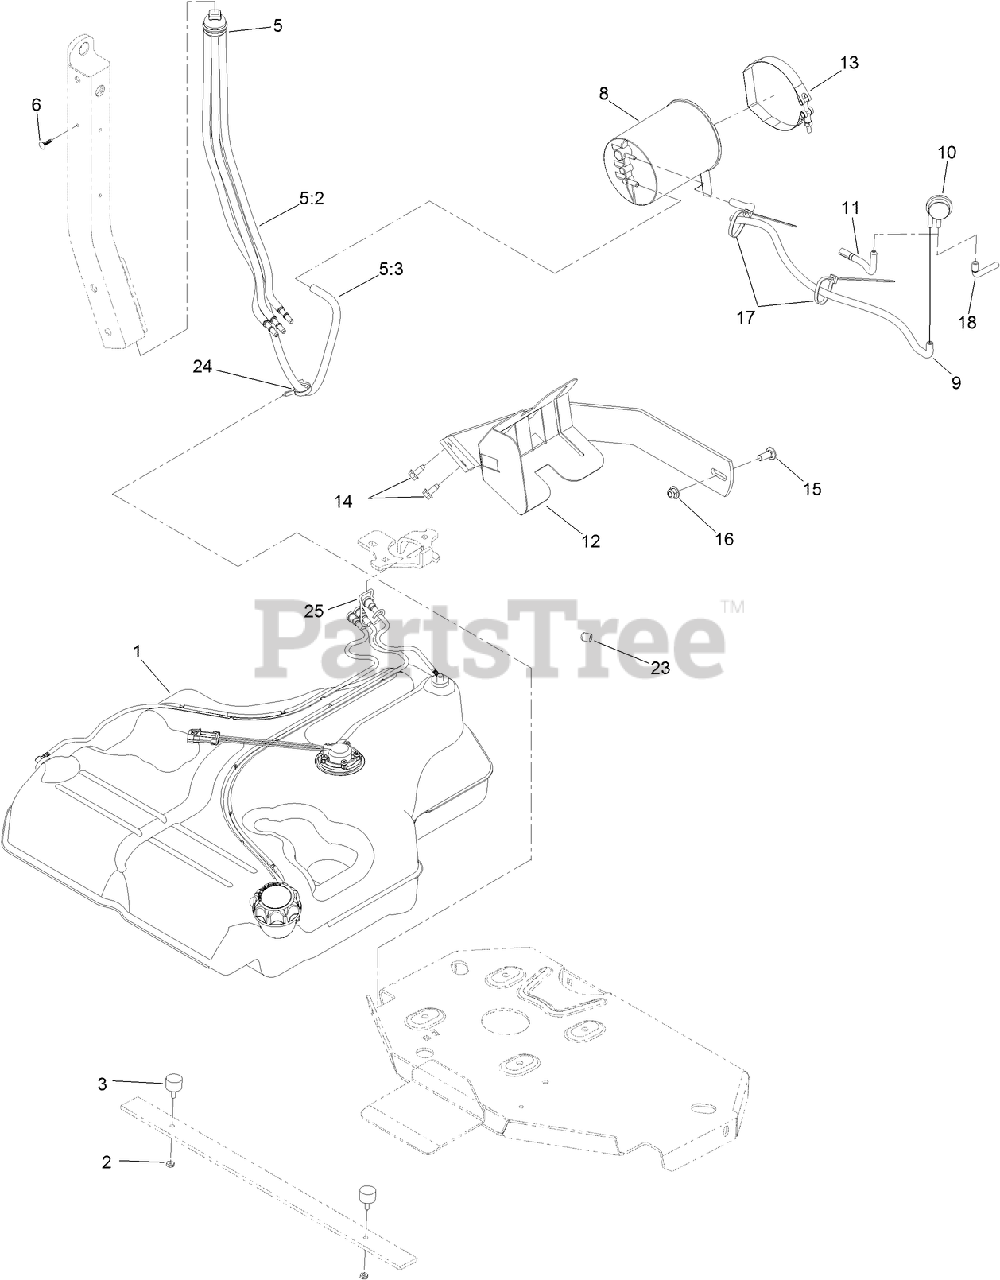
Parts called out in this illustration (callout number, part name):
2	NUT-JAM
5	FUEL MANIFOLD VENT ASM
5:2	HOSE-FUEL
5:3	HOSE-FUEL
6	PLUG-PLASTIC
8	CANISTER-CARBON, 1200CC
9	HOSE-VENT, FORMED
10	VALVE-CONTROL, VACUUM
11	HOSE-VENT, FORMED
12	MOUNT-CANISTER
13	CLAMP, T-BOLT
14	SCREW-HWHTF
15	SCREW-CARR
16	NUT-HF, NI
17	TIE-PLASTIC
18	HOSE-VENT, FORMED
23	PLUG-PORT
24	CLAMP-HOSE
25	RETAINER-LINE, VAPOR
